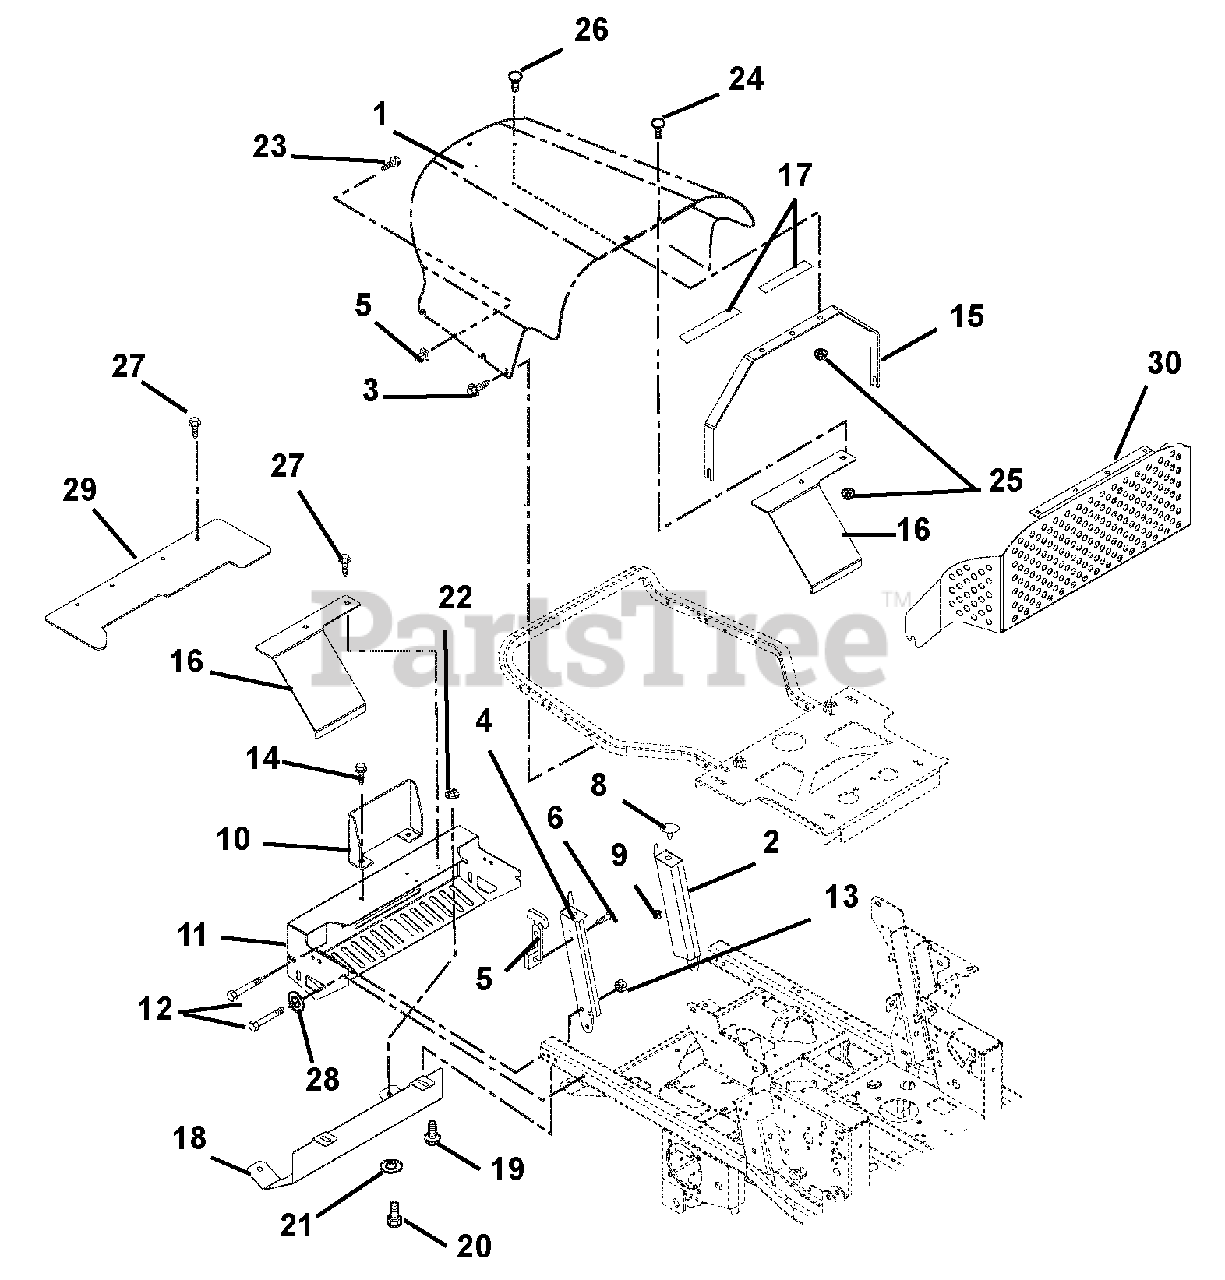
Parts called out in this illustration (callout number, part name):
2	Weldment, Hood Support, Left Hand
3	Screw, Tapping .38-16 x .75 Hex Washer Head
4	Weldment, Hood Support Right Hand
5	Latch, Rubber
6	Screw, Machine 10-24 x .50 Hex Washer Head
7	Screw, Machine 10-24 x 1.50 Hex Washer Head
8	Button Bumper
9	Nut-Spin Lock-Flange .312-18
10	Guard, Muffler (992148, 149, 150, 151, 152, 153, 154, 155, 157, 159)
11	Bumper, Rear
12	Bolt, Hex .38-16 x 2.75 Grade 5
13	Nut-Locking-Top-Flange .38-16
14	Screw, Tapping .38-16 x .75 Hex Washer Head (992148, 149, 150, 151, 152, 153, 154, 155, 157, 159)
15	Hood Support (992152, 157, 159)
16	Guard (992152, 157, 159)
17	VHB Tape 4941F
18	Heat Shield
19	Screw-Tapping .38-16 x .50 Hex Washer Head Thread Rolling YWZ
20	Bolt-Hex .38-16 x .75 Grade 5
21	Washer-Flat-Steel .438 x1.00X.083 YWZ
22	Nut-Locking-Top-Flange .38-16
23	Screw-Machine 10-24 x 1.50 Hex Washer Head
24	Bolt, Round Head Square Neck .25-20 x .50 Grade 5 (992146, 147, 148, 149, 150, 151, 153, 154, 155)
25	Nut, Locking Top Flange .25-20 (992146, 147, 148, 149, 150, 151, 153, 154, 155)
26	Bolt, Round Head Square Neck .25-20 x .75 Grade 5
27	Screw, Tapping .25-20 x .50 Hex Washer Head Thread (992152, 157, 159)
28	Washer, Flat Steel .406 x .812 x .065
29	Shield, Heat (992146, 147)
30	Plenum- Hood (992146, 147, 148, 149, 150, 151, 153, 154, 155)
